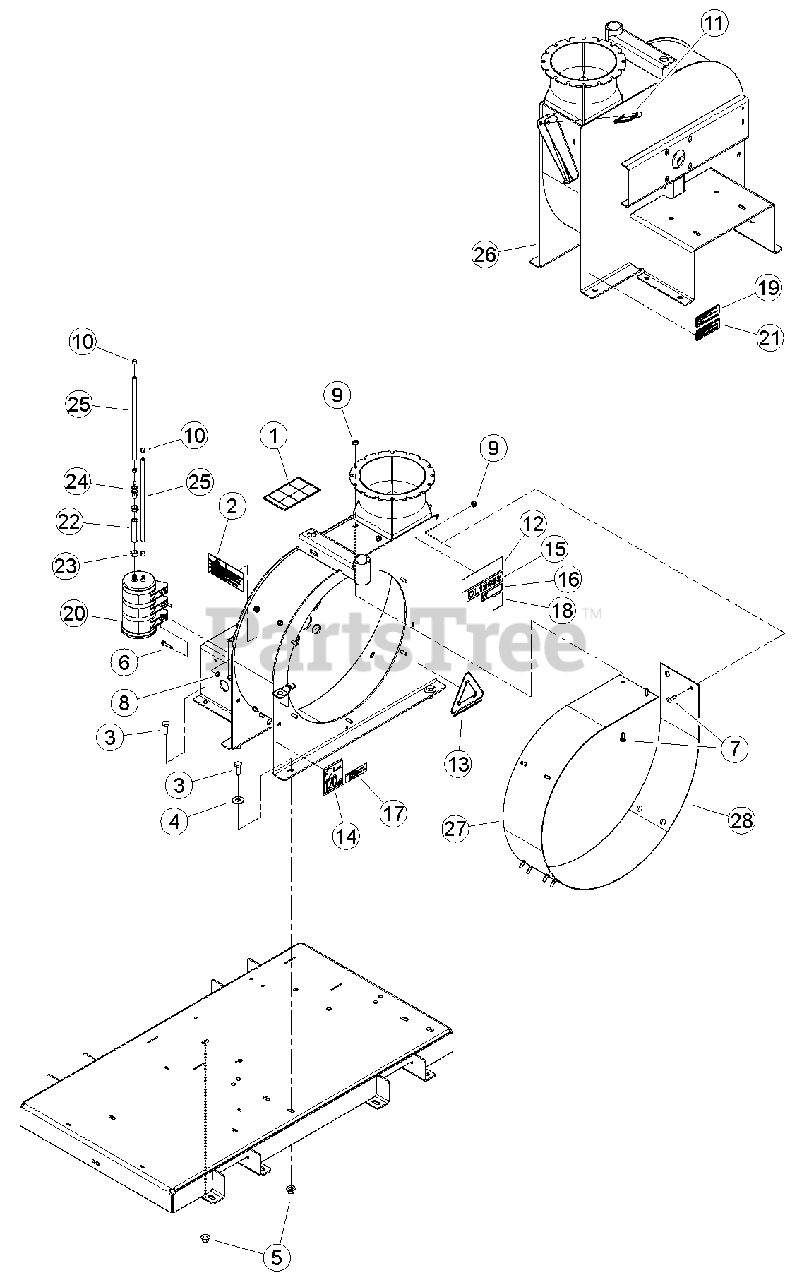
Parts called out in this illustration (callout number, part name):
1	DECAL, OPERATING INSTRUCTIONS ISO
2	DECAL, MUTILINGUAL MANUAL
3	BOLT, 1/2 X 1-1/4" GR5 HHCS NC ZP
4	WASHER, 1/2" FLAT ZP
5	NUT, 1/2-13 NYLOCK FLANGE
6	BOLT, 1/4 X 1-1/4 FLANGE NC
7	BOLT, 5/16 X 1" GR5 CRG ZP
8	NUT, 1/4-20 NYLOCK-FLANGE
9	NUT, 5/16-18 NYLOCK-FLANGE
10	CLAMP, 15/32 SPRING
11	PIN, 3/8 X 2-3/4" SNAP
12	DECAL, ECHO BEARCAT 6.82 X 1.90
13	DECAL, COLLECT IT
14	DECAL, 120 DB
15	DECAL, MODEL DL12653
16	DECAL, DL12653 INFORMATION
17	DECAL, ATLANTIC BRIDGE LTD INFO
18	DECAL, ECHO BEARCAT QR CODE
19	DECAL, EPA EVAP
20	CARBON CANISTER, 1000CC
21	DECAL, CARB EVAP
22	HOSE, 1/2 X 3" FUEL LINE
23	CLAMP, SPRING 1/2" ID HOSE
24	FITTING, REDUCER 1/2" TO 1/4" BARB
25	HOSE, 23" FUEL
26	WELDMENT, FAN HOUSING
27	WRAP, HOUSING FAN
28	WRAP, HOUSING FAN
